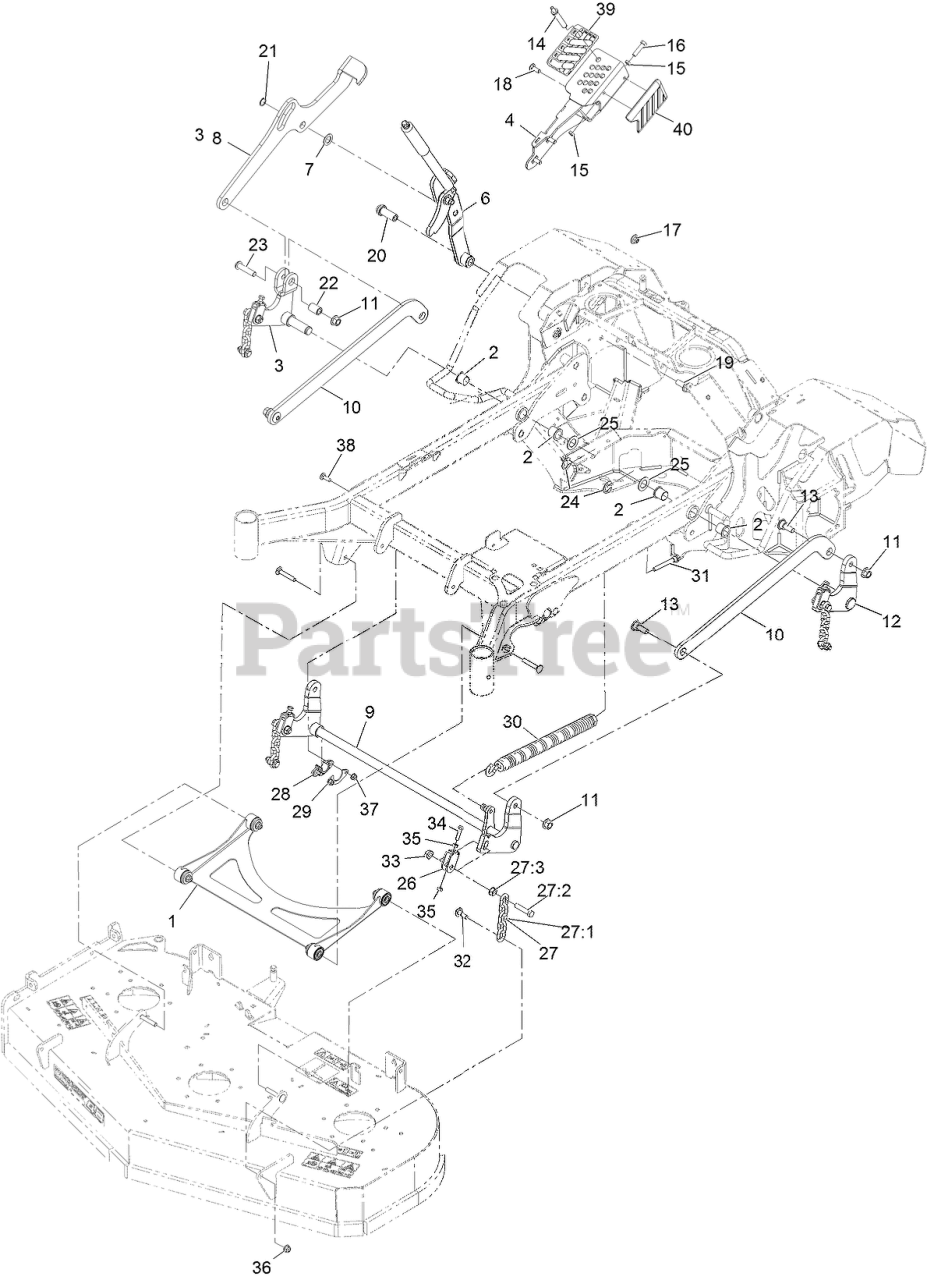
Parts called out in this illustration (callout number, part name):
1	ASM, Deck Strut
2	BUSHING, IGUS
3	Weld, Bellcrank, Rt
4	Weld, HOC Index
6	ASM, HOC Lever
7	WASHER-THRUST
8	Strap, HOC Index
9	Weld, HOC Cross Shaft
10	Strap, HOC Lift
11	Nut-Lock 1/2-13
12	Weld, Bellcrank
13	Bolt, Shoulder
14	PIN-HOC
15	NUT-JAM
16	BOLT-HH
17	Nut-Nyloc 3/8-16 Flg
18	SCREW-CARR
19	HUB-THREADED
20	SCREW-HH
21	RING-SNAP
22	Spacer, HOC
23	Screw-HSBH
24	RING-RETAINING, EXT
25	Washer-Flat
26	YOKE-ADJUST, DECK
27	DECK LIFT CHAIN ASM
27:1	CHAIN-LIFT, DECK
27:2	SCREW-HH
28	BUSHING-FLANGE
29	GUSSET-LIFT, DECK
30	SPRING-EXTENSION
31	BOLT-SHOULDER
32	SCREW-SHOULDER, HHF
34	SCREW-HH
35	NUT-JAM
36	NUT-HF, NI
37	NUT-HF, NI
38	BOLT-CARR
39	Decal-Height Of Cut
40	Pad, Knee
